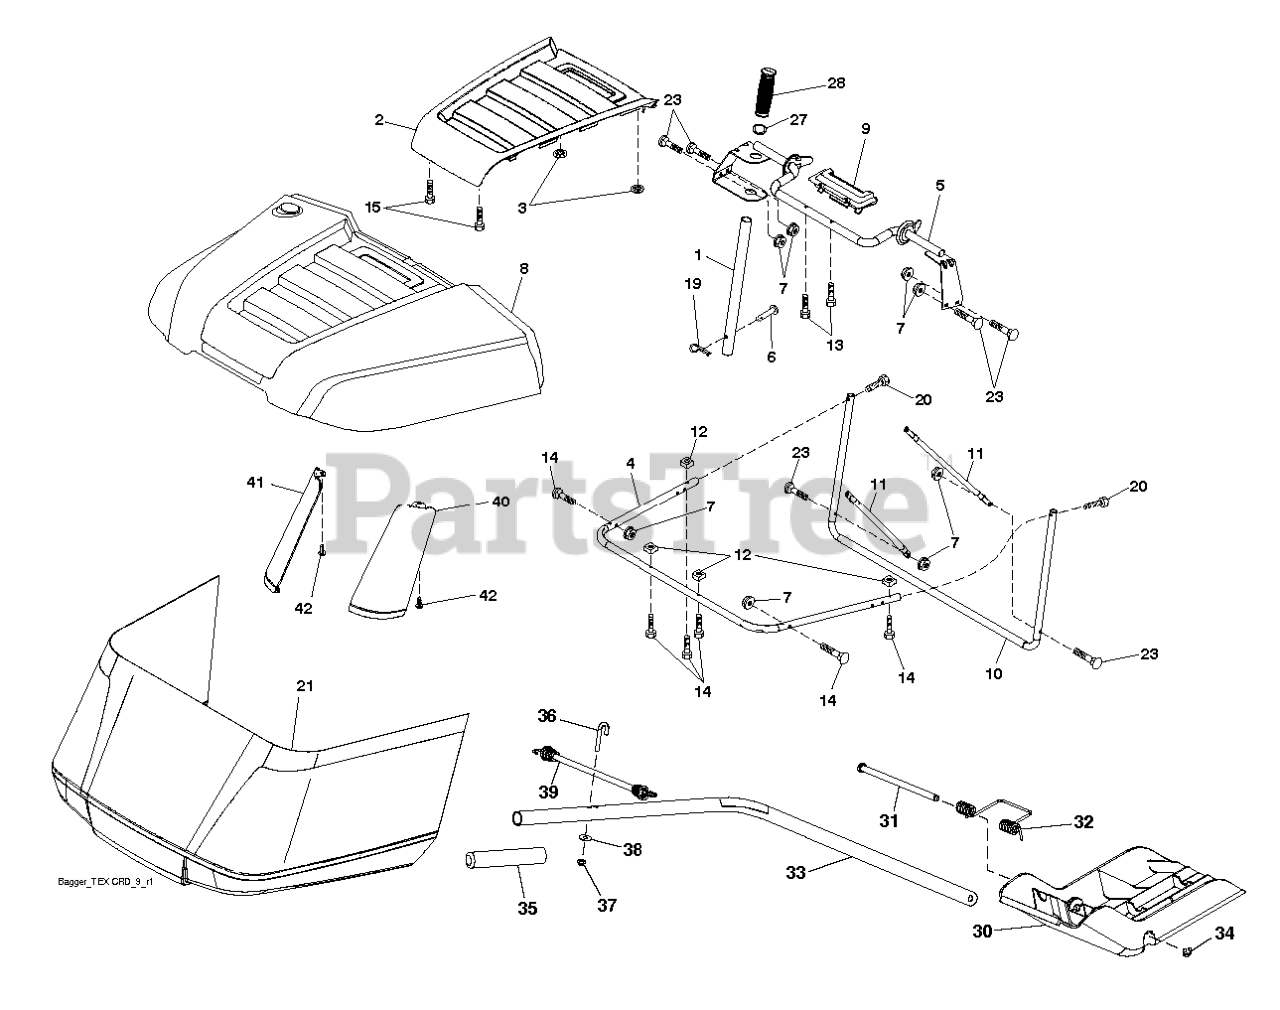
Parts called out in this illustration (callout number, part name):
1	TUBE.HANDLE.BAGGER.CRD/SRD.BLA
2	APPLIQUE.TOP.BAG.SRD.ORANGE
3	NUT.PUSH.156
4	SUBASM.TOP.TUBE.TEX.CRD
5	FRAME.ASM.TOP.BAGGER.SRD
6	RIVET,DRILLED
7	NUT T
8	BAGGER.TOP.SRD.APPLIQUE
9	INSERT.HANDLE.BAGGER.(2 2)
10	FRAME FRAME.FRONT.TEX.CRD
11	BRACE BRACE SIDE TUBE
12	NUT.SQUARE.1/4
13	SCREW.1/4X1.150.HXWSH
14	BOLT.SHOULDER.HX.WSH.1/4X1.150
15	SCREW,#8.FLAT.HEAD.DRILL.TIP
19	PIN.COTTER.5/16.BOW TI
20	SCREW.HEXCAP.1/4-20X1.375(2 2)
21	BAG SUBASM. TEX CRD GEN 2 HUSQ
27	RB GROMMET.RUBBER.SRD
28	GRIP.HANDLE.BLACK
30	PLUG PLUG
31	PIN PIN.HINGE
32	SPRING SPRING DOUBLE TORSION
33	SHAFT SHAFT TEX CRD MULCH PLU
34	E-RING.5/16"
35	GRIP GRIP MULCH PLUG HAND
36	BOLT BOLT J
39	BUBGEE BUBGEE TEX CRD
42	CLIP CHRISTMAS TREE CLIP
